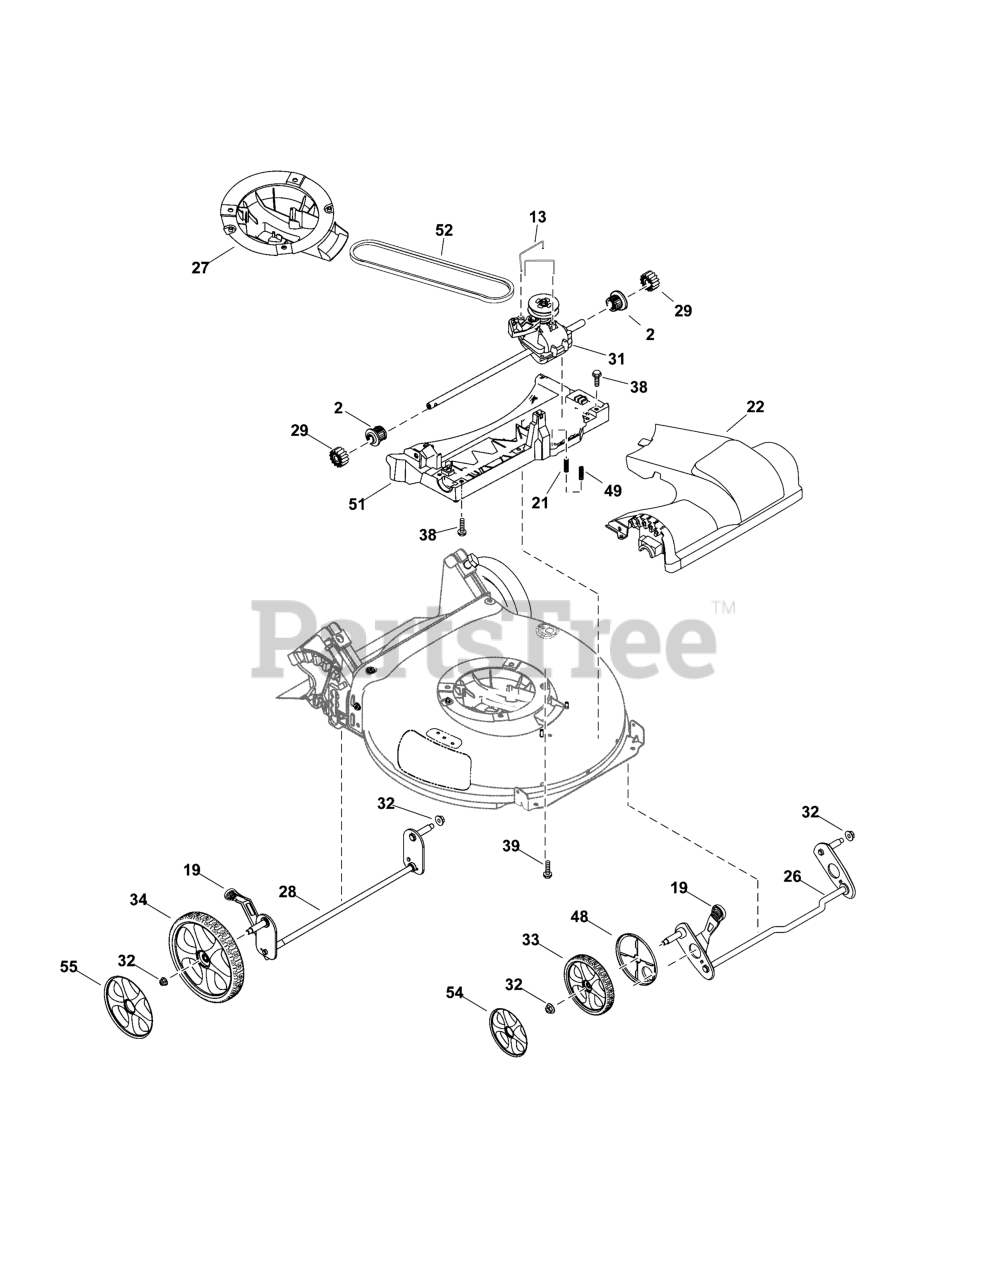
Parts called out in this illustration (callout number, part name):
2	ASSEMBLY, Bearing
13	WIRE, Transmission
19	KNOB, Adjustment Lever
21	SPRING, Compression
22	COVER, Front
26	AXLE ASSEMBLY, Front
27	BAFFLE, Engine
28	AXLE ASSEMBLY, Rear
29	GEAR, Spur
31	TRANSMISSION ASSEMBLY
32	NUT, Hex Flange, Nylock, 3/8-16
33	WHEEL, Front
34	WHEEL, Rear
38	SCREW, 1/4-15X3/4, Self-Tapping, BZ
39	SCREW, Shoulder, 1/4-20 x 1/2
48	COVER, Dust, Wheel
49	SPRING BODY
51	TRAY, Lower
52	V-BELT, 3L, 34.13, V-SPD
